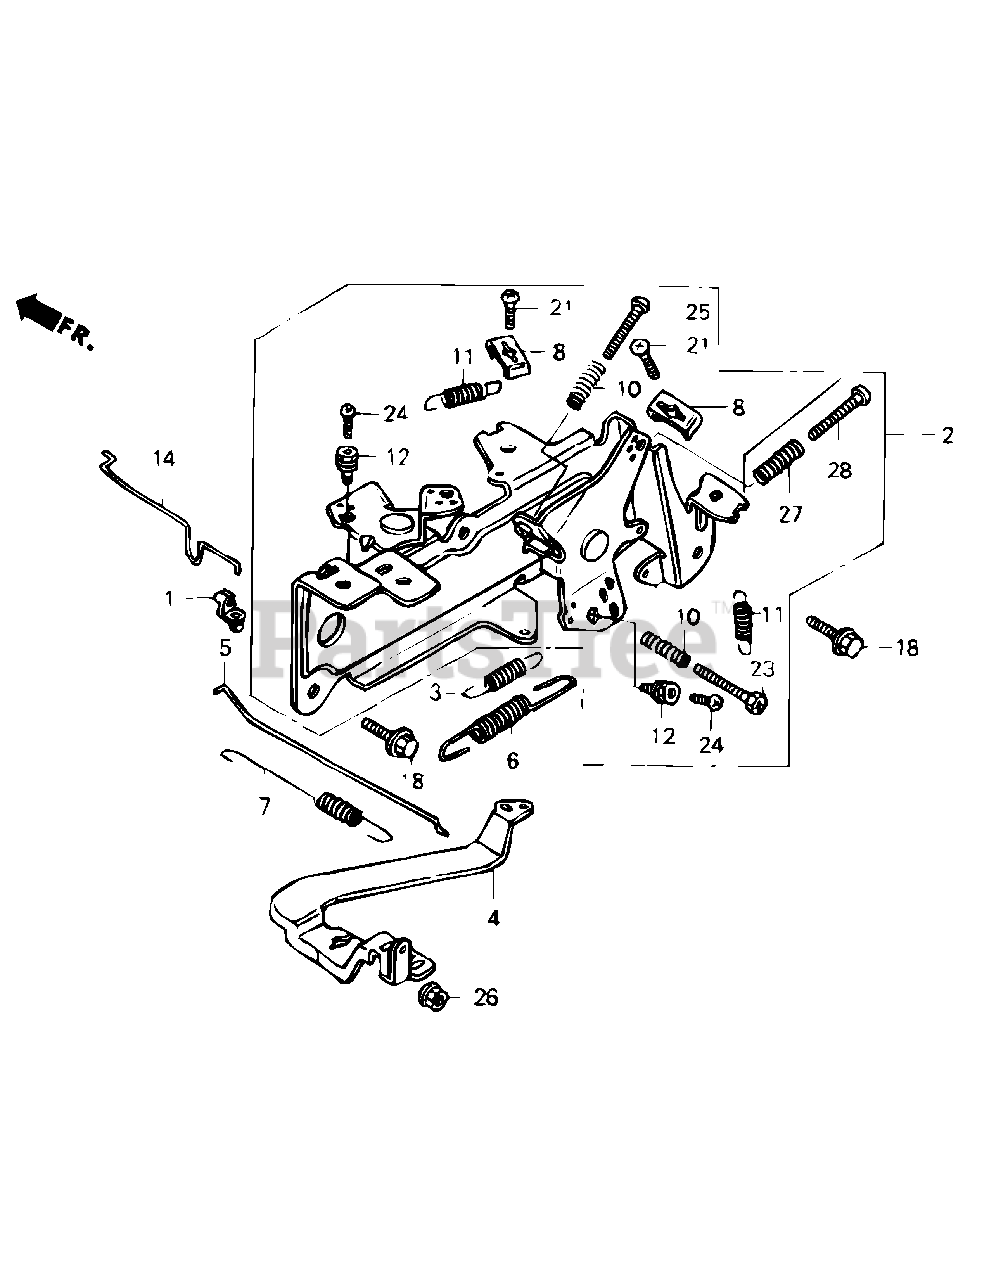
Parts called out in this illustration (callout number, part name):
1	Joint, Rod
2	Control Assembly
3	Spring, Starter
4	Arm, Governor
5	Rod, Governor
6	Spring, Governor
7	Spring, Throttle Return
8	Holder, Cable
10	Spring, Control Adjusting
11	Spring, Cable Return
12	Holder, Cable
14	Rod, Choke Control
18	Bolt, Flange (6x14)
21	Bolt, Slot (5x16)
23	Bolt, Slot (5x25)
24	Bolt, Recessed (4x6)
25	Screw, Pan (5x25)
26	Nut, Flange (6mm)
